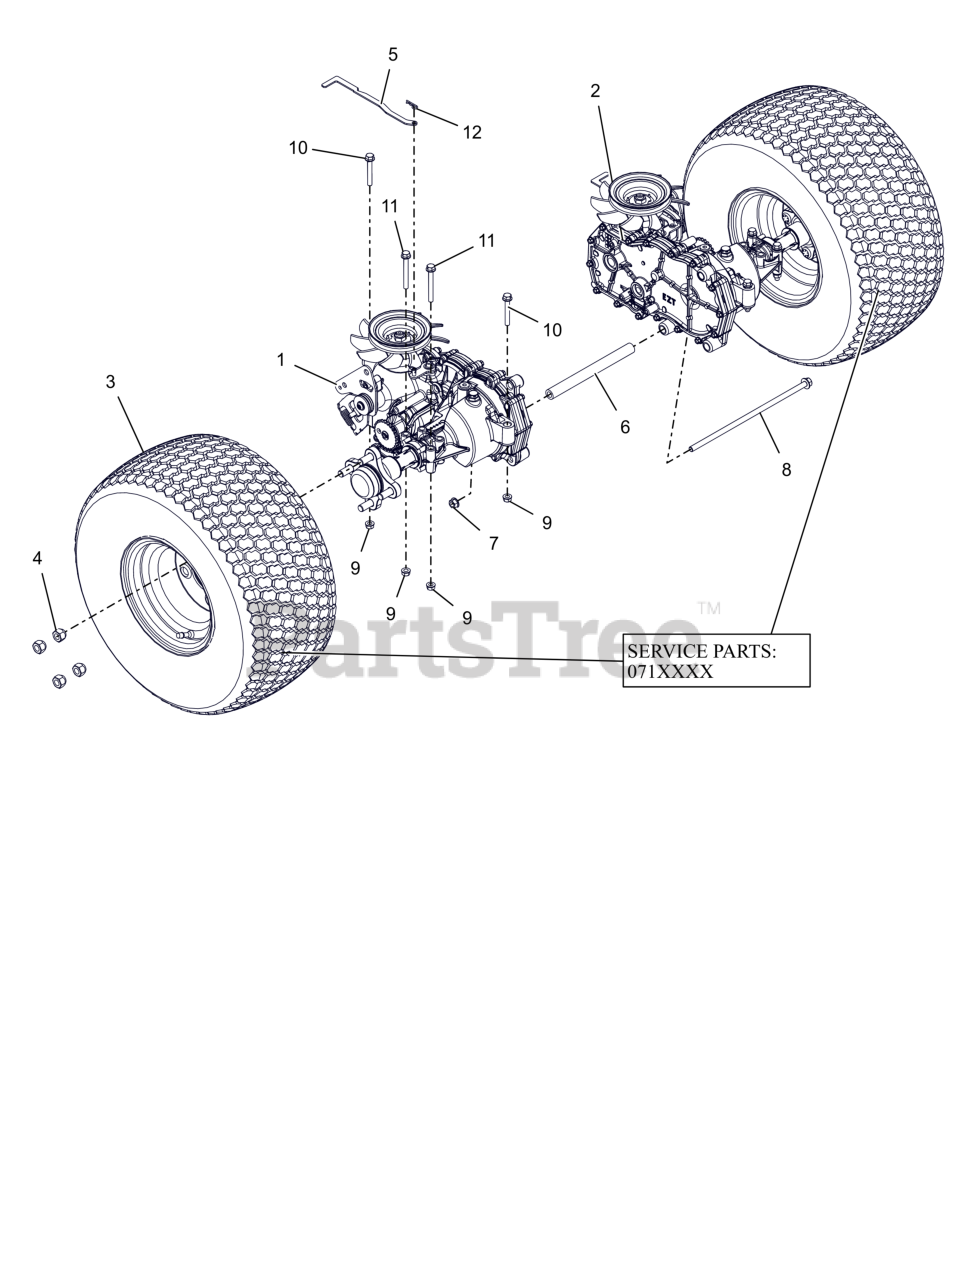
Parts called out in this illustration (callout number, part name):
1	TRANSAXLE, RH
2	TRANSAXLE, LH
3	ASSM TIRE\WHEEL, 20 X 10 -8
4	NUT, WHEEL .50-20 ZCC
5	BRKT, DUMP VALVE
6	SPCR, TRANSAXLE .438 ID X .750 OD X 8.18 (BLACK)
7	NUT-LK-CTR-FLG .375-16 GF ZCC
8	BLT, HEX-FLG 0.375-16X11.5 GR5 ZC120
9	NUT,LK-CTR-FLG .31-18 GF ZCC
10	BLT,HEX-FLG .31-18X2.25 G5 ZCC
11	BLT,HEX-FLG .31-18X2.75 G5 ZCC
12	PIN, HAIR #213 .08X1.19 ZCC
